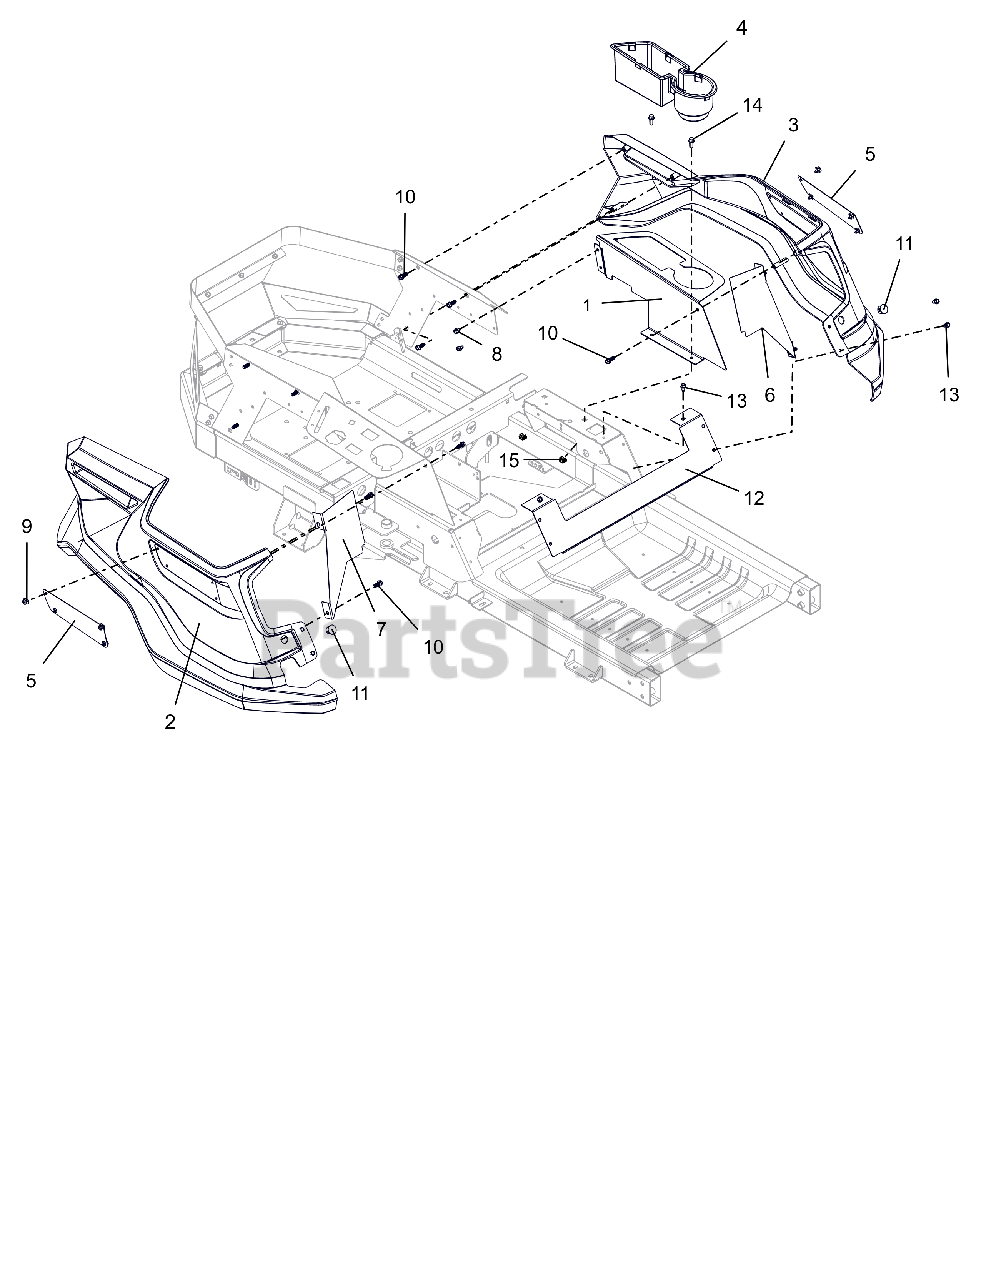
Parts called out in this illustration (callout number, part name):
1	PANEL, LEFT SIDE FENDER MOUNT
2	FENDER, RH IKON
3	FENDER, LH IKON
4	INSERT, CUP/STORAGE HOLDER
5	PLATE, ARIENS NAME
6	PLATE, LH BLOCKER
7	PLATE, RH BLOCKER
8	SCR,TAP .25-20X.375 HWH TR ZCC
9	RIVET, PLASTIC .195 DIA.
10	SCR-.312X.75 #14H H/W/H H/L CZ
11	PLUG, HOLE .75 (BLACK)
12	PLATE, SEAT KICK
13	SCR-TAP .25-20X.50 HWH ZCC
14	BLT,HEX-FLG .25-20X.75 G5 BFP
15	NUT RETNR .25-20
